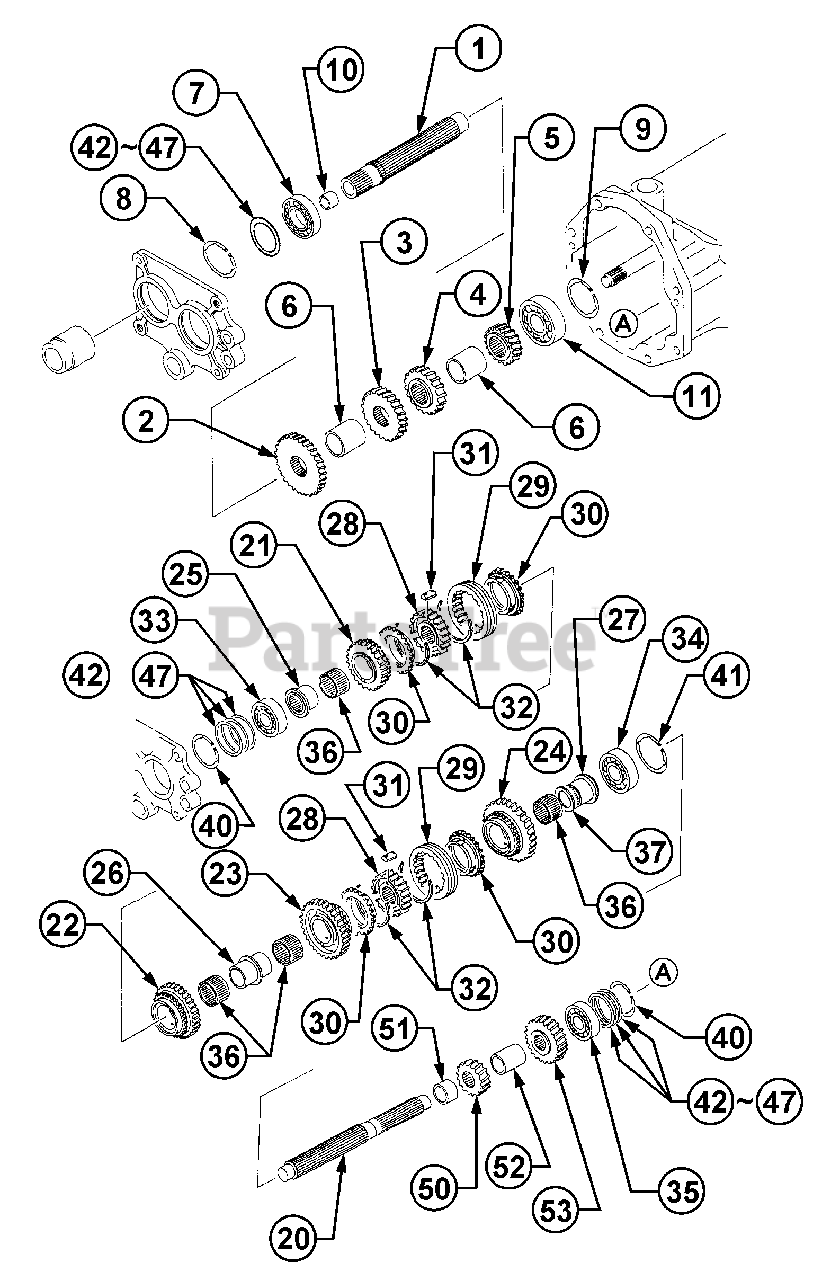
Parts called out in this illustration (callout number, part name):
7	Bearing, Ball
11	Bearing, Ball
33	Bearing, Ball
34	Bearing, Ball
35	Bearing, Ball
36	Bearing, Needle
42	Liner, t=0.15
